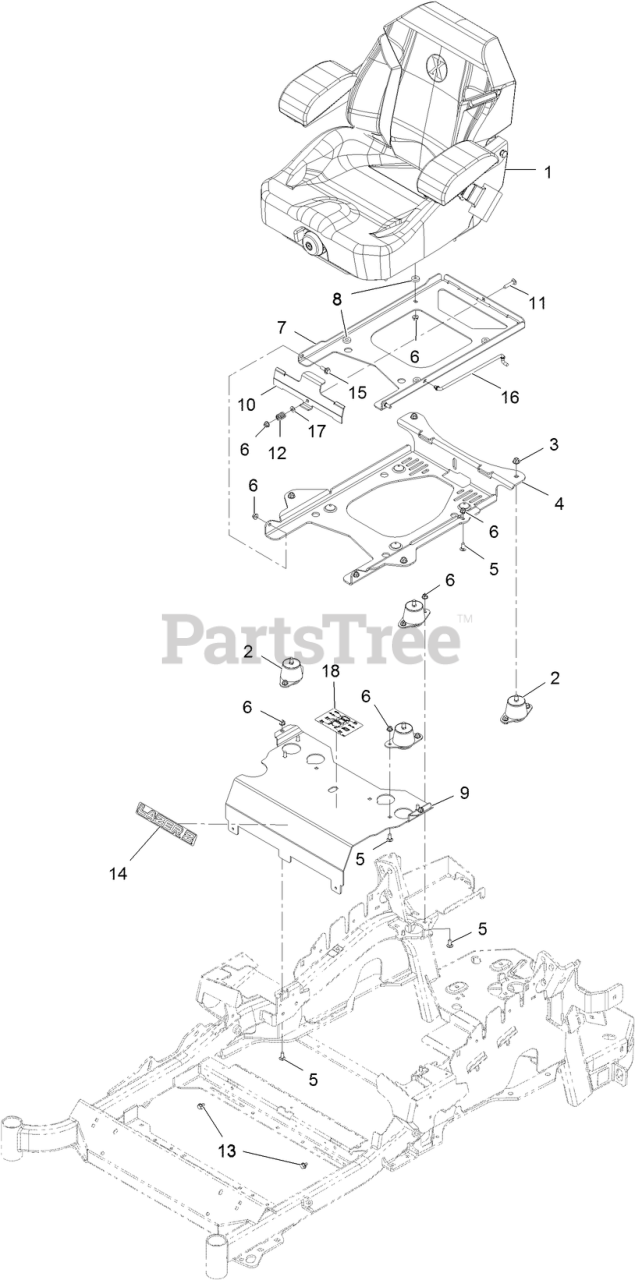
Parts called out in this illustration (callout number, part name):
1	KIT-SUSPENSION SEAT
2	ISOLATOR-SEAT
3	NUT-HF, NI
4	PLATE-TILT, SEAT SUPPORT
5	SCREW-CARR
6	NUT-HF, NI
7	PLATE-FRAME, SEAT
9	Panel-Front, Seat Mount
10	PLATE-LATCH, SEAT
11	BOLT-CARR
12	SPRING-COMPRESSION
14	DECAL, LAZER MODEL
15	SCREW-SHOULDER
16	ROD-PROP
17	WASHER-PLAIN
18	DECAL-SERVICE AID
